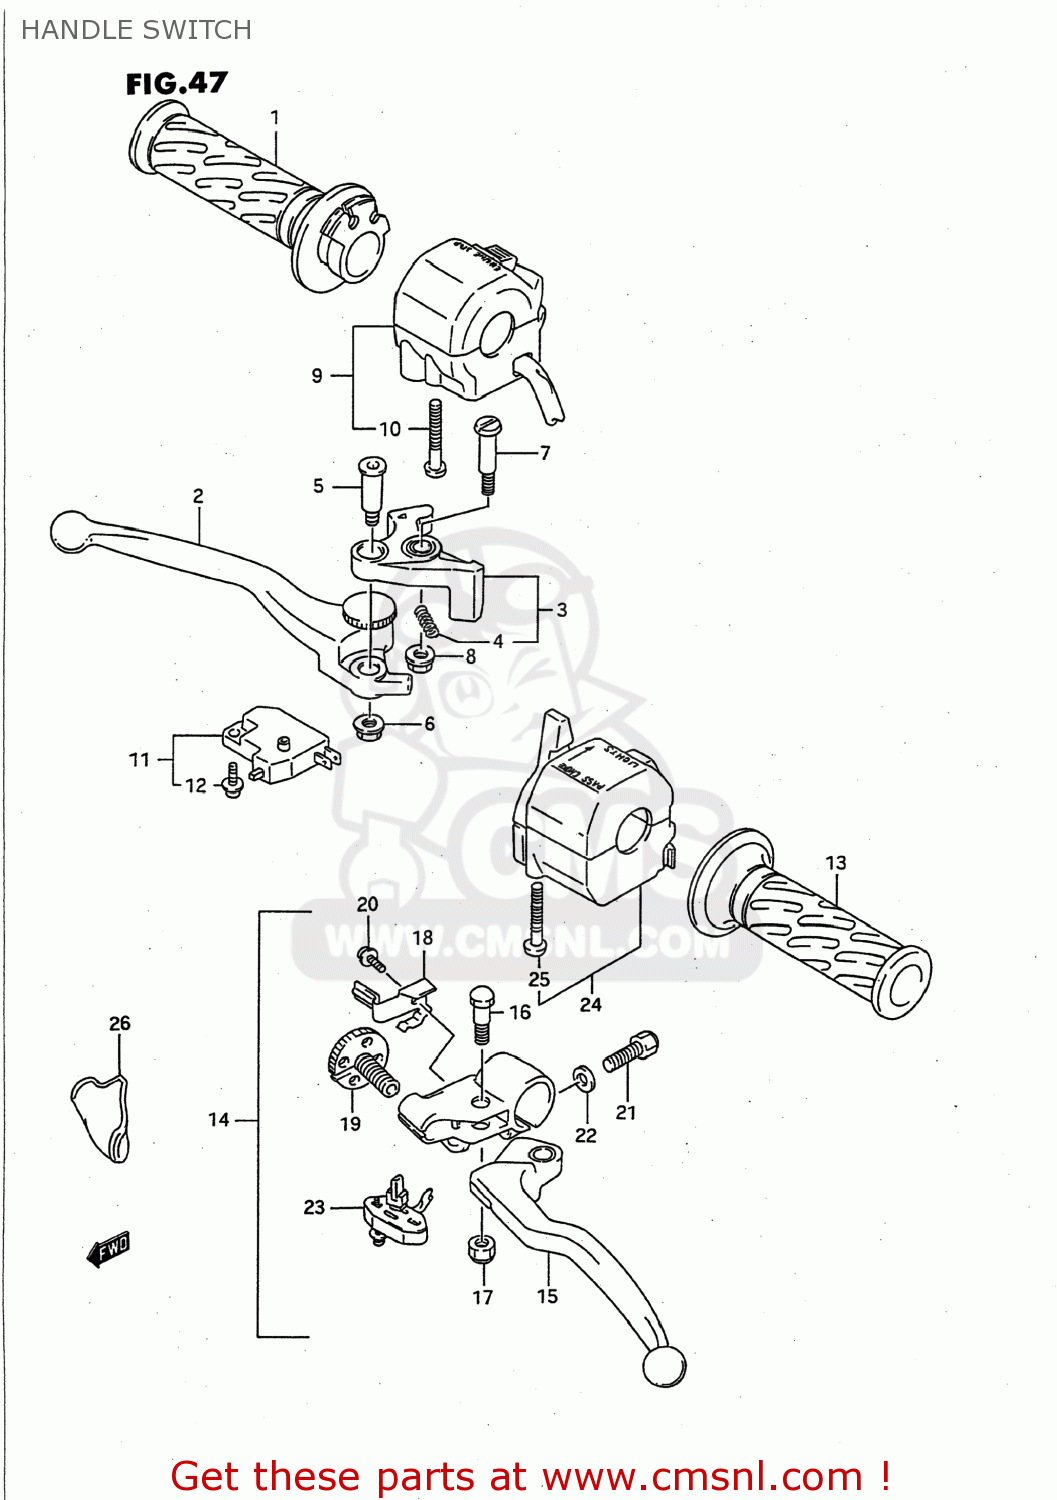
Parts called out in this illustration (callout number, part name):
1	GRIP,THROTTLE
2	LEVER,ADJUST
3	KNOCKER
4	SPRING
5	BOLT,LEVER
6	NUT
7	BOLT,LEVER PIVOT
8	NUT 6MM
9	SWITCH ASSEMBLY,HANDLE,RIGHT
10	SCREW, 5X45
11	SWITCH ASSEMBLY,STOP
12	SCREW
13	GRIP,LEFT
14	LEVER ASSY,CLUTCH
15	LEVER,CLUTCH
16	BOLT,LEVER PIVOT
17	NUT
18	ADJUST,SPRING
19	ADJUSTER,LOCK
20	SCREW
21	BOLT
22	WASHER
23	SWITCH ASSY,CLUTCH
24	SWITCH ASSY,HANDLE,L
25	SCREW, 5X45
26	COVER,CLUTCH LEVER
